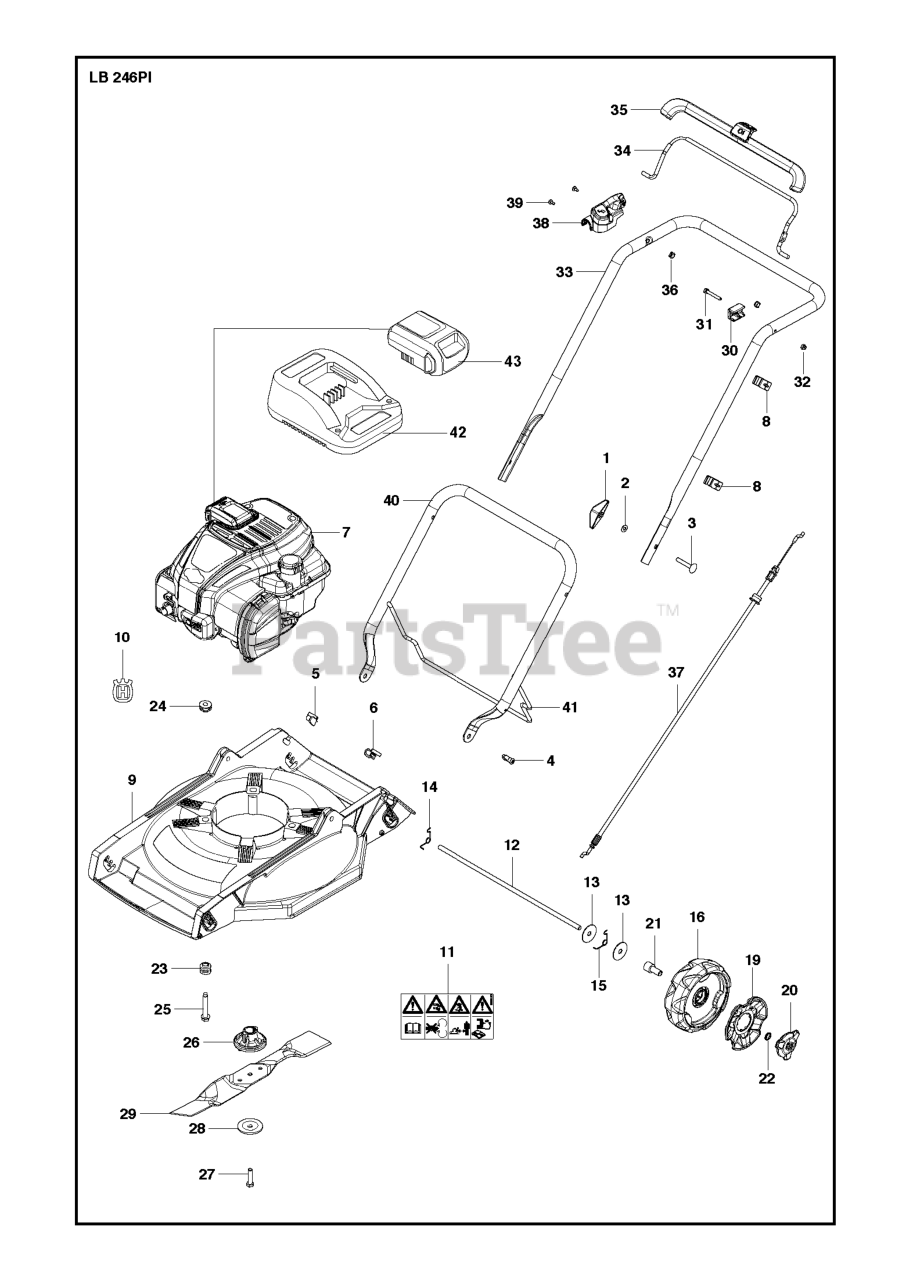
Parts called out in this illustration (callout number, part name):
1	WINGNUT
32	NUT FLANGE - M6
39	SCREW
